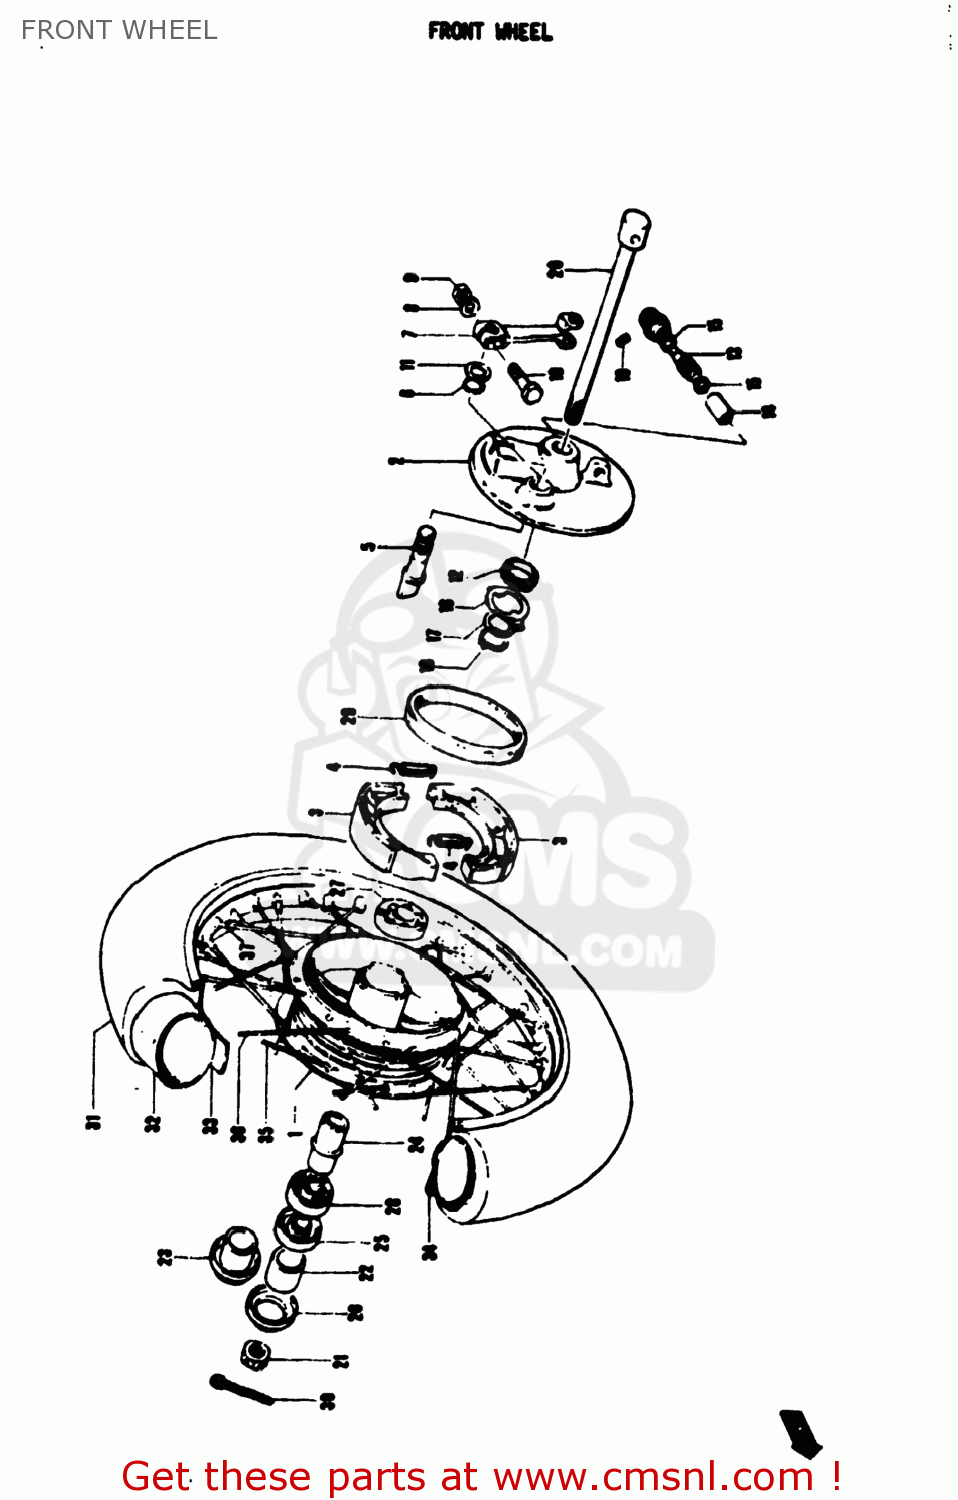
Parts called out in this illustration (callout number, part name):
1	HUB,FRONT
2	PANEL,FRONT BRAKE ANCHOR
3	SHOE,BRAKE
4	SPRING(L:34)
5	CAM,FRONT BRAKE
6	O RING(D:2.5,ID:11.4)
7	LEVER,FR BRAKE CAM
8	WASHER
9	NUT
10	BOLT
11	WASHER(12.5X20X1)
12	GEAR,SPEEDOMETER
13	PINION,SPEEDOMETER
14	BUSH,METER GEAR OUTER
15	WASHER (5.1X9X0.4)
16	DRIVER,SPEEDOMETER GEAR
17	WASHER(16X22X1)
18	SCREW
19	CIRCLIP
20	AXLE,FRONT
21	NUT
22	SPACER(10X15X12.4)
23	SPACER,FRONT AXLE,RIGHT
24	SPACER,FRONT HUB BEARING
25	SEAL,OIL(15X31X5)
26	COVER,FRONT HUB DUST S
27	BEARING, LH
28	BEARING
29	OIL SEAL (43X58X7)
30	COTTER PIN
31	TIRE
32	TUBE,INNER
33	PROTECTOR,WHEEL,INNER
34	SPOKE SET,REAR
35	SPOKE,WHEEL
36	SPOKE,WHEEL
37	NIPPLE,SPOKE
